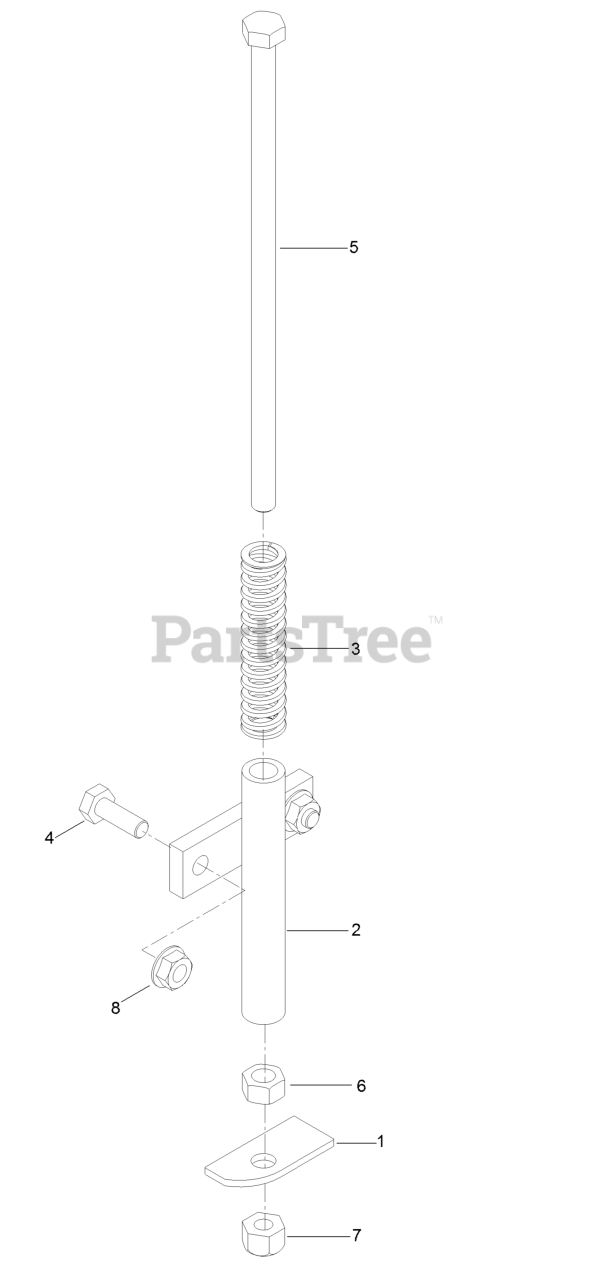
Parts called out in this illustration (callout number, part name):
1	Plate-Switch
2	Mount-Spring, Seat
3	Spring-Switch, Seat
4	Screw-HH
5	Screw-HH
6	Nut-Hex
7	Nut-Lock, NI
